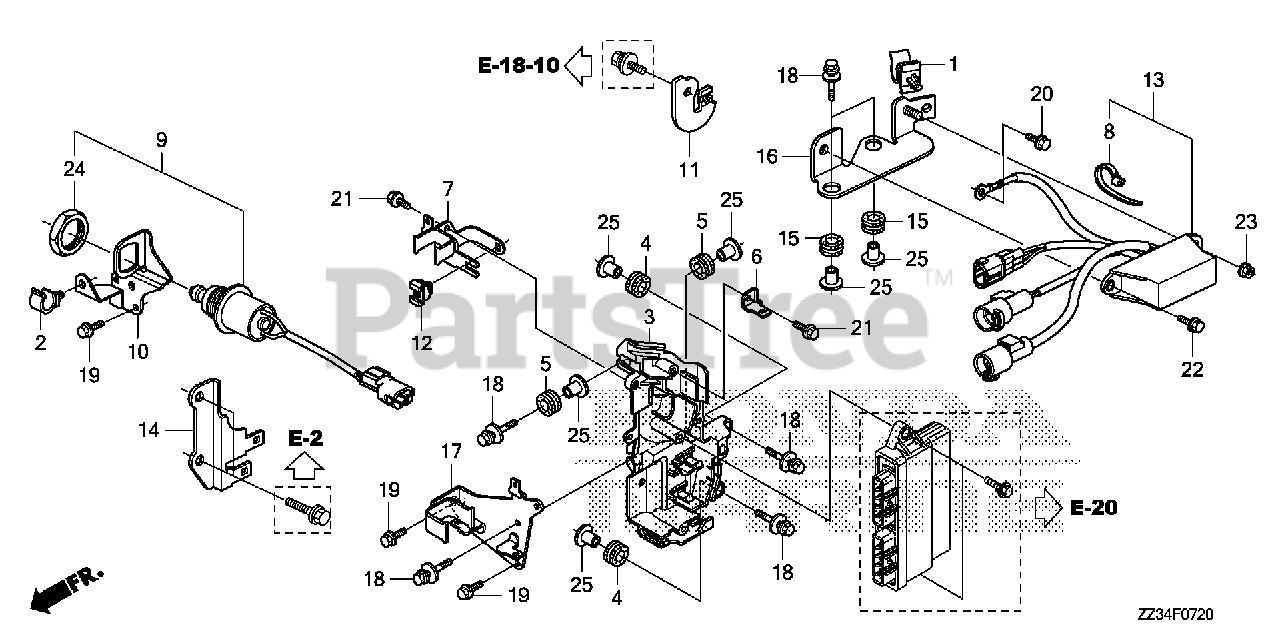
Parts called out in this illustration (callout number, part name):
1	CLAMP, FUEL TUBE
2	CLAMP B, FUEL TUBE
3	CASE, ELECTRONIC PARTS
4	GROMMET, ELECTRONIC PARTS CASE
5	GROMMET, MODULE IGNITION CONTROL CASE (CDI)(B)
6	BRACKET, ALTERNATOR FUSE
7	BRACKET, FUSE
8	TIE, CABLE (2.4X92) (NATURAL)
9	SWITCH ASSY., NEUTRAL
10	BRACKET, NEUTRAL SWITCH
11	BRACKET, POWER TILT SWITCH CONNECTOR
12	CLIP, CONNECTOR HOLDER (B)
13	RELAY ASSY., POWER TILT
14	BRACKET A, POWER TILT CONNECTOR
15	GROMMET, RELAY BRACKET
16	BRACKET, POWER TILT RELAY
17	BRACKET, MAIN RELAY
18	BOLT-WASHER (6X27) (CT200)
19	BOLT, FLANGE (6X14) (CT200)
20	BOLT, FLANGE (6X12)
21	BOLT, FLANGE (6X10)
22	BOLT, FLANGE (6X14)
23	NUT, FLANGE (6MM)
24	NUT, HEX. (20MM)
25	COLLAR, MODULE IGNITION CONTROL CASE (CDI)
